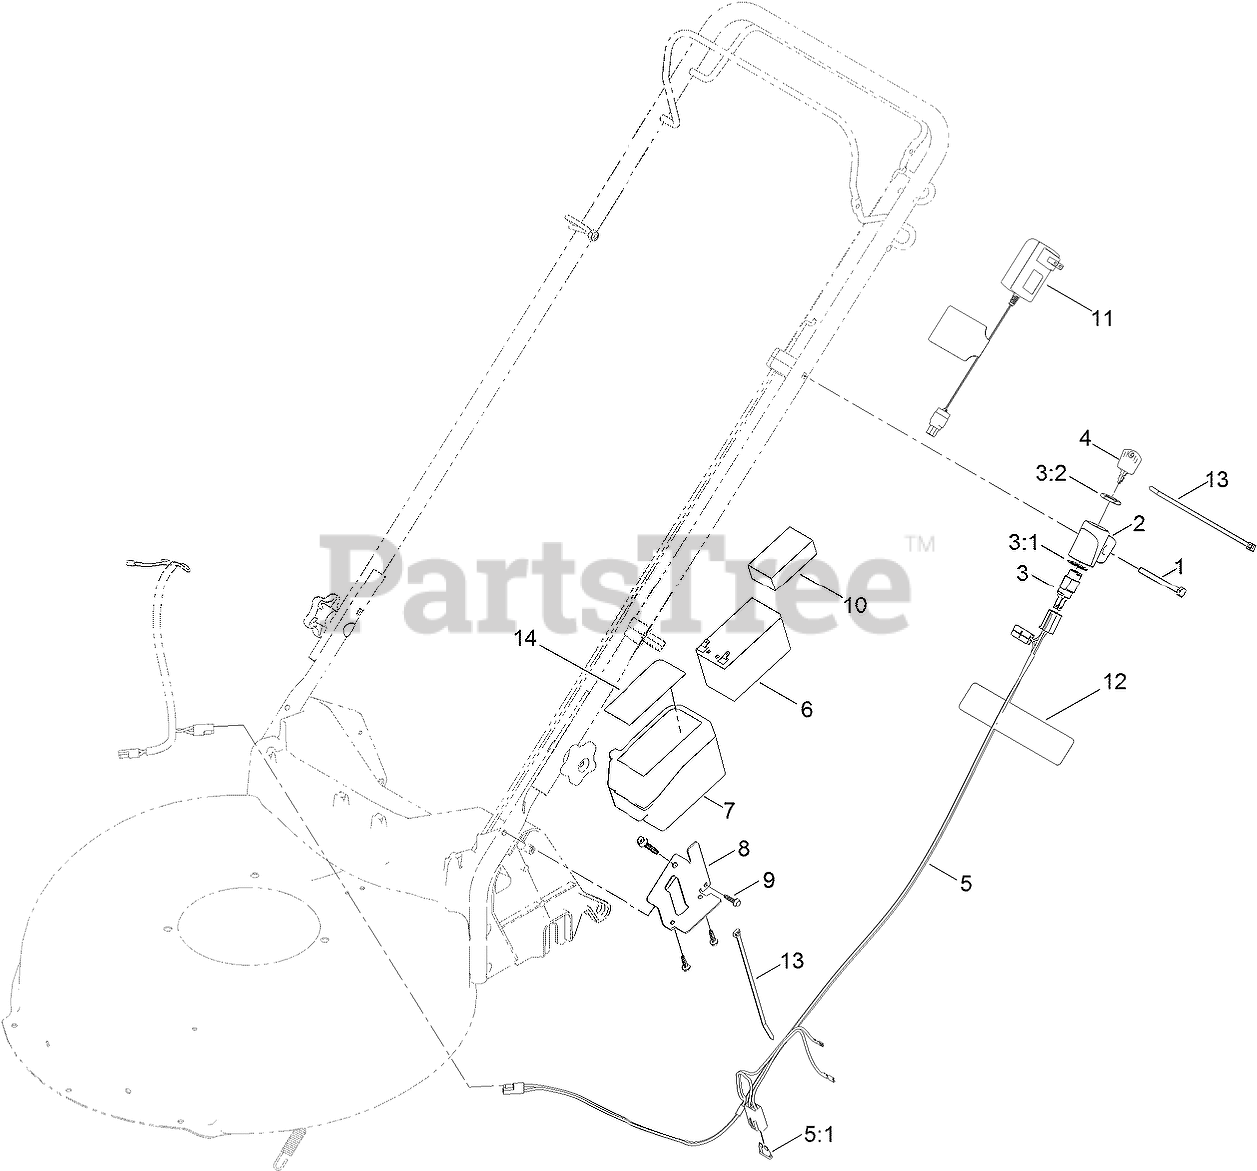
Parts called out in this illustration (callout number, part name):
1	SCREW-HH
2	MOUNT-SWITCH
3	STARTER SWITCH ASM
3:1	WASHER-LOCK
3:2	NUT-HH
5	HARNESS-WIRE
5:1	FUSE-40 AMP
6	BATTERY-NONSPILLABLE, 12 V
7	BATTERY BOX ASM
8	BRACKET-BATTERY
9	SCREW-PLASTIC, HWH
10	FOAM-BATTERY, TOP
11	CHARGER, BATTERY (12V, CE)
11	CHARGER, BATTERY (12V, UK)
12	DECAL-BATTERY CHARGING
13	TIE-CABLE
14	DECAL-BOX, BATTERY
